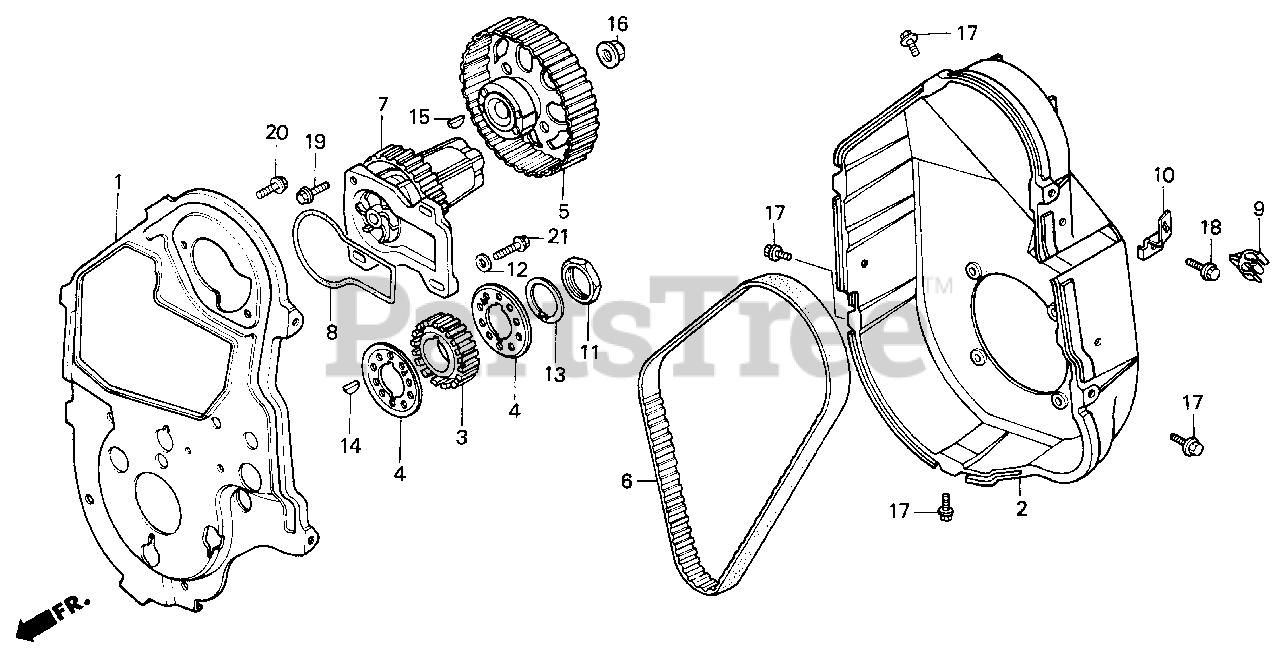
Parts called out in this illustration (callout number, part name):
1	COVER B, TIMING BELT
2	COVER A, TIMING BELT
3	PULLEY, TIMING
4	FLANGE, TIMING PULLEY
5	PULLEY, CAMSHAFT
6	BELT, TIMING
7	WATER PUMP
8	O-RING, WATER PUMP
9	CLIP, RECEIVER PIPE
10	BRACKET, IGNITION WIRE CLIP
11	NUT, LOCK (30MM)
12	WASHER, PLAIN (6.5X15)
13	WASHER, LOCK (30MM)
14	KEY, SPECIAL WOODRUFF (25X18)
15	KEY, CAM PULLEY
15	KEY, WOODRUFF (16X12)
16	NUT, FLANGE (10MM)
17	BOLT, FLANGE (6X10)
18	BOLT, FLANGE (6X12)
19	BOLT, FLANGE (6X22)
20	BOLT, FLANGE (6X12)
21	BOLT, FLANGE (6X22)
